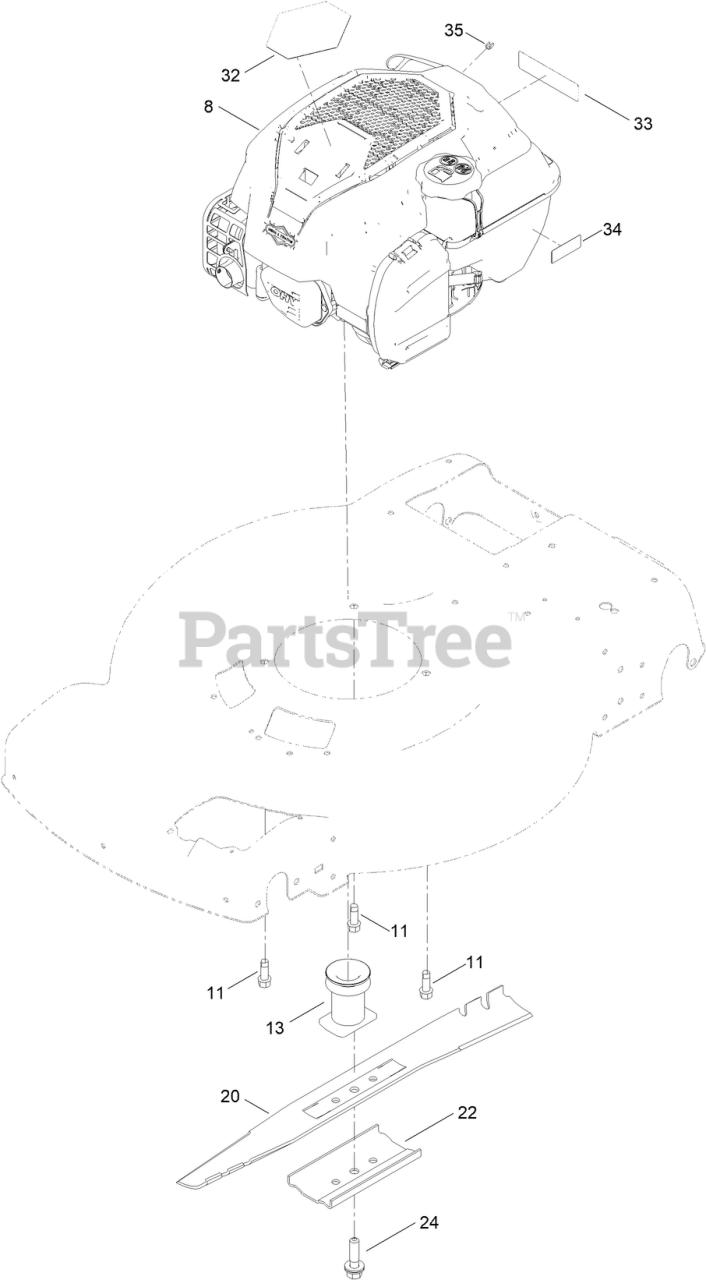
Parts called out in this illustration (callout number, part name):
11	SCREW-THD FORM, HWH
13	DRIVER-BLADE
20	BLADE-22 INCH
22	SUPPORT-BLADE
24	BOLT-BLADE
32	DECAL-BRIGGS 725 EXI SS
33	DECAL-ARRESTOR, SPARK
34	DECAL-LEVEL, FUEL
35	STOP-ROPE
